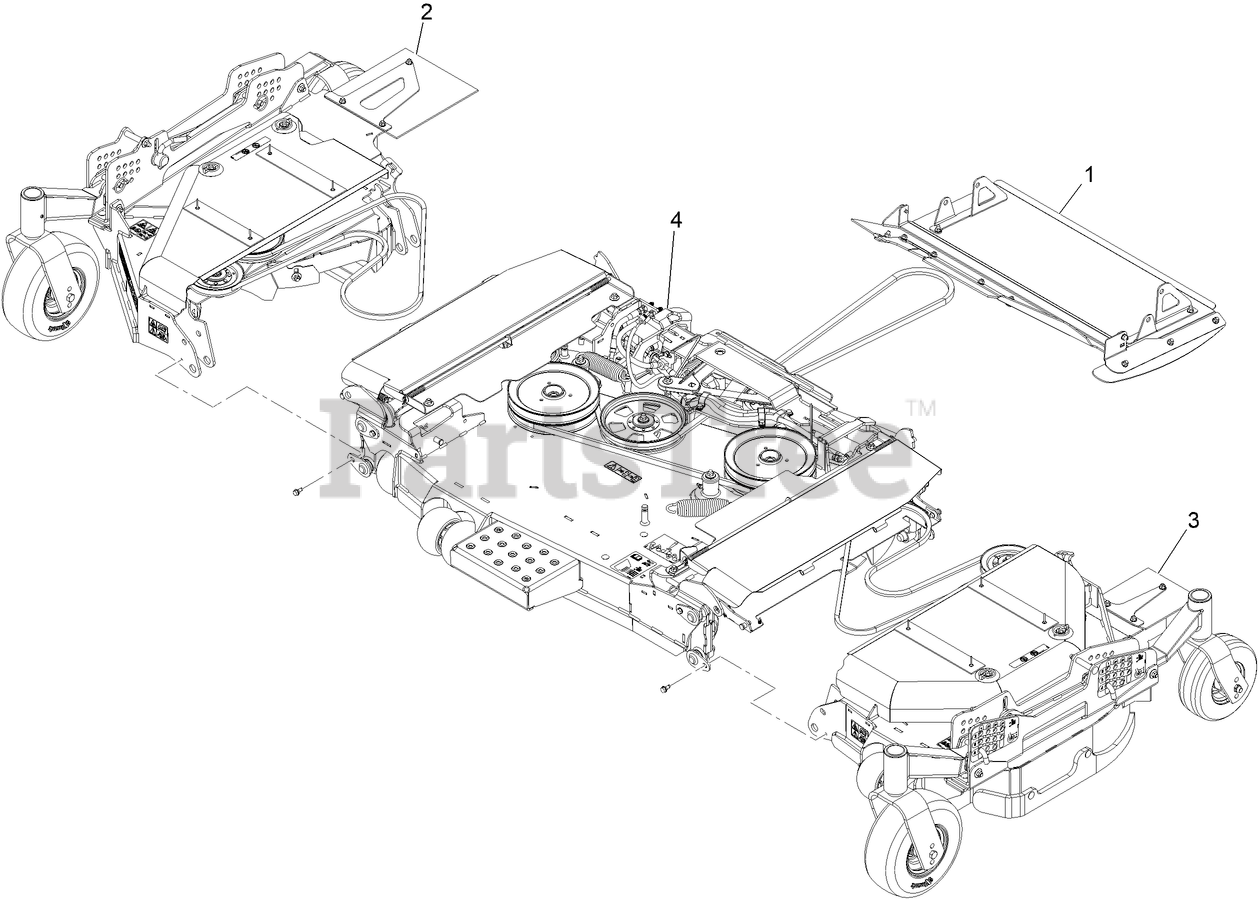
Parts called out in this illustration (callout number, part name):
1	Discharge-Tunnel ASM, 96-Gas
2	ASM-Deck, RH Wing 96G
3	ASM-Deck, LH Wing 96G
4	ASM-Deck, Ctr 96G
